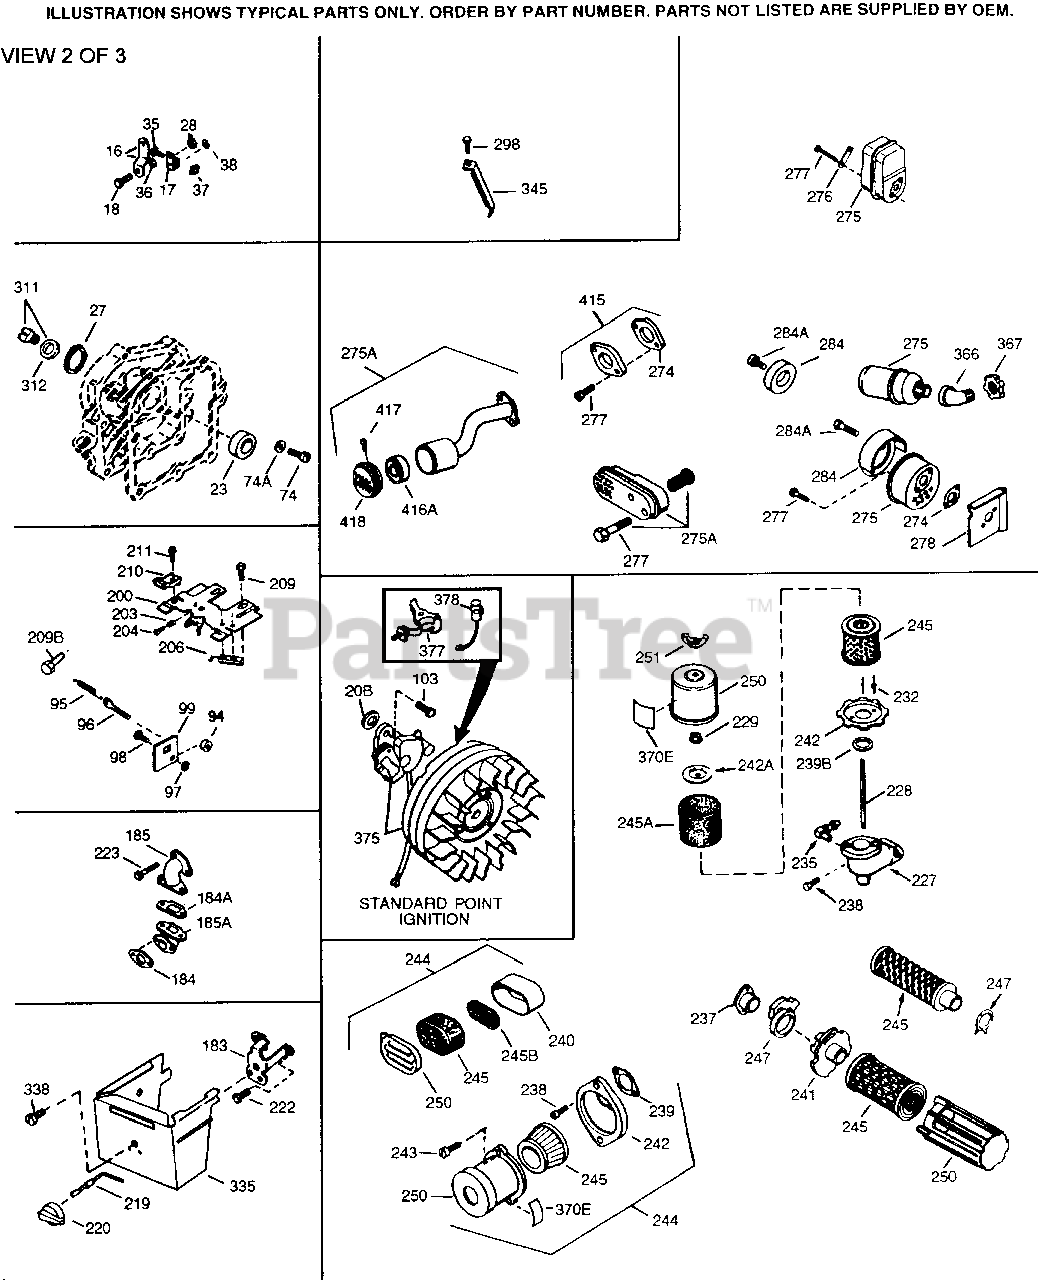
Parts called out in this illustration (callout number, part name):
16	Governor Lever
17	Governor Lever Clamp
18	Screw, 8-32 x 5/16"
103	Screw, Torx T-15, 10-24 x 1"
131	Screw, 5/16-18 x 1-1/2"
184	* Carburetor To Intake Pipe Gasket
185	Intake Pipe
200	Control Bracket Incl. 203,204,206,209 ,209A
203	Compression Spring
204	Screw, 5-40 x 7/16"
206	Terminal
223	Screw, 1/4-20 x 1"
237	Air Cleaner Adaptor
238	Screw, 10-32 x 7/16"
239	Air Cleaner Gasket
241	Air Cleaner Collar
245	Air Filter (Paper) (also available in Packaged Part #740095 (Qty.2))
247	Air Cleaner Clamp
250	Air Filter Cover (Craftsman)
274	* Exhaust Gasket
275	Muffler
277	Screw, 1/4-20 x 1-3/4"
284	Muffler Deflector
284A	Screw, 1/4-15 x 3/4"
298	Screw, 1/4-15 x 7/8"
311	Oil Fill Plug (Incl. 312) also availa ble in Packaged Part #740079
312	* Oil Fill Plug Gasket
345	Heat Baffle
999	Summer Maintenance Kit (incl. Oil, Sp ark Plug, Air Cleaners (2), & Ultra-F resh)
